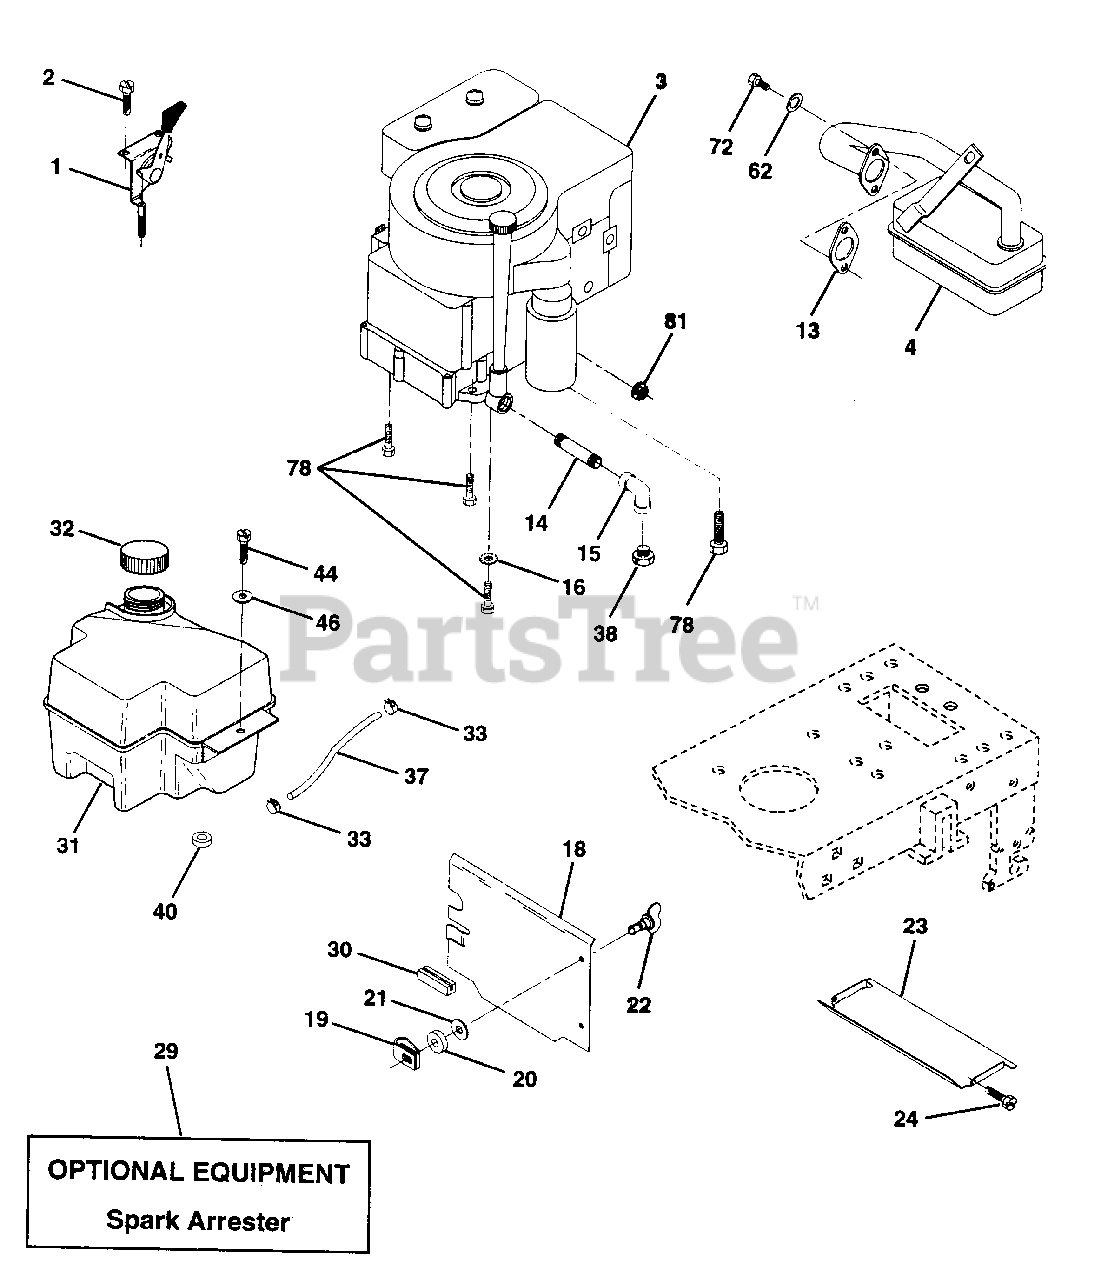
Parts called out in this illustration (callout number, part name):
1	Control Th/ch 23 5 LH Flag
2	Screw Hex Thd Cut 1/4-20x5/8 T
4	Muffler Exh Lt B&S 14 HP IC OHV
13	Gasket Eng 1 313 Id Tin Plated
14	Nipple Pipe 3/8 Npt X 3"
15	Elbow Std 90 Degree 3/8-18 Npt
16	Washer Lock Ext Tooth 3/8
18	Shield Heat Lt
19	Receptacle 1/4 turn
20	Retainer 1/4 turn
21	Washer 9/32 x 5/8 x 16 Ga.
22	Stud 1/4 turn
23	Shield Heat Browning LT/YT
24	Screw Tap Hex #10-24unc X 1/2
29	Kit Spark Arrestor (Flat Scrn)
30	Pinch Weld Hood Black
31	Tank Fuel Front 2 00
32	Cap Asm Fuel W/sym Vented
33	Clamp Hose Black
37	Line Fuel 20"
40	Bushing Snap Nyl Blk Fuel Line
44	Screw Hexwsh Thdrol 1/4-20x3/4
46	Washer 9/32 X 7/8 X 16 Ga
62	Washer Lock Hvy Hlcl Spr 5/16
72	Screw Hexhd Cap 5/16-18x 3/4
78	Screw Thdrol 3/8-16x1-1/4 TYTT
81	Nut Keps Hex 1/4-20 UNC
